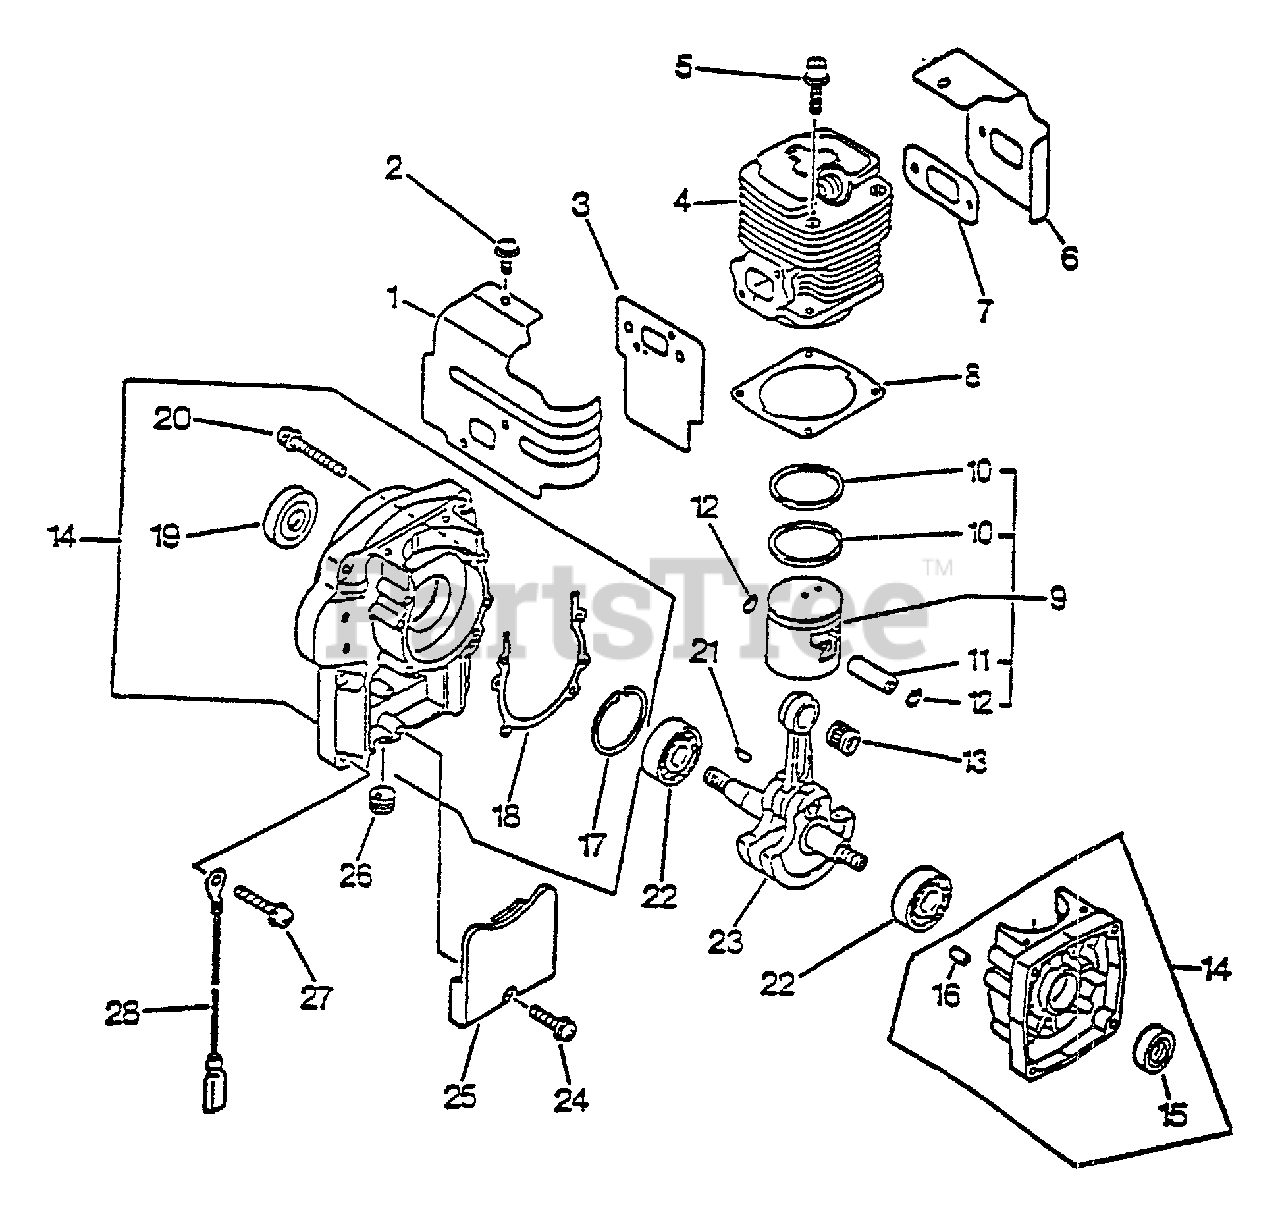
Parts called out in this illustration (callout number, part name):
1	COVER, CYLINDER - INTAKE
2	SCREW - 5X10
3	GASKET, INTAKE
4	CYLINDER
5	SCREW - 5X20
6	COVER, CYLINDER
7	GASKET, EXHAUST
8	GASKET, CYLINDER
9	PISTON KIT
10	RING, PISTON
11	PIN, PISTON
12	RING, RETAINING - 8
13	BEARING, NEEDLE
14	CRANKCASE KIT
15	SEAL, OIL
16	PIN - LOCATING
17	RING, RETAINING - 35
18	GASKET, CRANKCASE
19	SEAL, OIL
20	SCREW - 5X40
21	KEY - 3X14
22	BEARING, BALL - 6202
23	CRANKSHAFT ASSY
24	SCREW - 5X16
25	COVER, DUST
27	SCREW - 5X32
28	LEAD - GROUND
